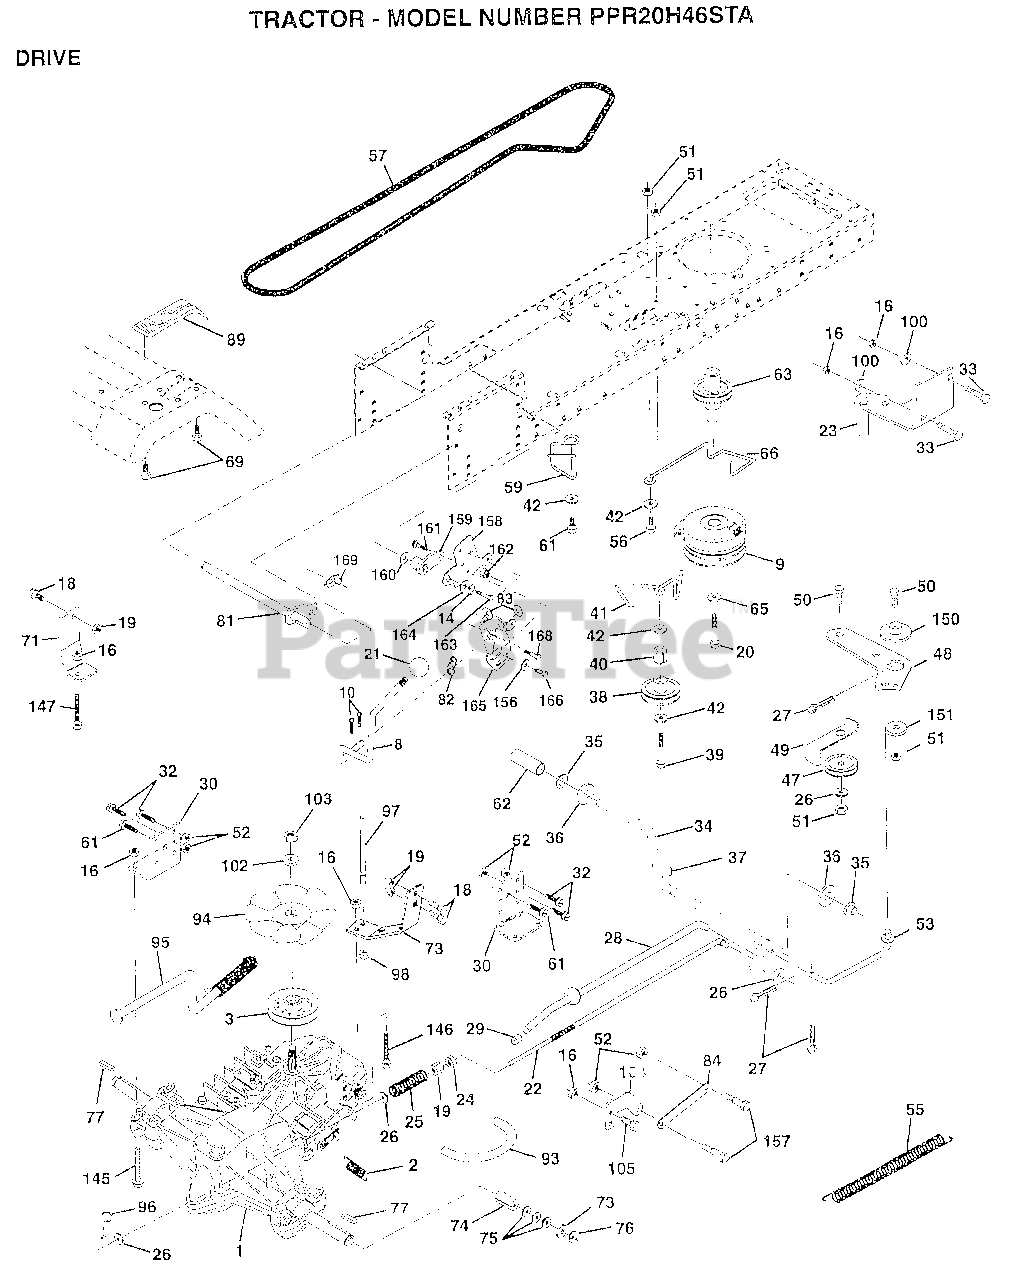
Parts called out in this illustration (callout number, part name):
2	SPRING RET BRAKE
3	PULLEY.TRANSAXLE
8	ROD.SHIFT.FEND.ADJ.YT
9	CLUTCH.ELECTRIC
10	PIN COTTER 1/8
14	LOCKWASHER
16	NUT
18	BOLT
19	NUT
20	BOLT.7/16-20X4.25
21	KNOB DLX BLK/BLK
22	ROD.BRAKE.HYDRO.
23	BRACKET.CLUT.MTG.
24	NUT
25	SPRING ROD LT
26	WASHER
27	COTTER PIN
28	ROD.BRAKE.PARK.LT
29	PLUNGER CAP T
30	TRANSAXLE MTG BKT
32	BOLT
33	BOLT
34	SHAFT ASM-PEDAL F
35	NYLON BEARING
36	WASHER LT
38	FLAT IDLER PULLEY
39	BOLT
40	SPACER T
41	"KEEPER,BELT.IDLER FLAT"
42	WASHER
48	BELLCRANK.CLUTCH
49	RETAIN BELT
53	"LINK, CLUTCH T"
55	"SPRING, RETURN LT"
57	"BELT.GD DRV 82"""
59	KEEPER BELT CNTSP
61	SCREW
62	PEDAL COVER T
63	PULLEY.CLUTCH.EVX
65	LOCKWASHER
66	KEEPER-BELT
69	SCREW HEXWSH H-L
71	STRAP TORQ LH HYD
73	"STRAP-TORQUE,RH"
74	SPACER SPLIT
75	WASHER
76	E-RING LT
77	SQUARE KEY
78	WASHER
81	SHAFT.ASM.CROSS
82	"SPRING,TORSION"
83	WASHER
84	LINK.TRANSAXLE.LT/YT
89	CONSOLE.SHIFT.AUTO.YT/GT.BLACK
93	"LINE FUEL HYD 4"""
94	"FAN 7"" HYDRO"
95	CONTROL.ASM.BYPASS.HYDRO.99
96	RETAINER M
97	BOLT KEEPER RH
98	NUT
100	WASHER M
102	WASHER BELLEVILLE
104	ARM CONTROL HYDRO
105	SCREW CAP 5/16-18
145	BOLT.HEX.FLGHD
146	BOLT.HEX.FLGHD.
147	BOLT.HEX.FLGHD
150	BUSHING.BELLCRANK.GRD.DR
151	WASHER
156	WASHER.SRRTD.5/16
157	"BOLT,SHOULDER"
158	BRKT.SHIFT.MOUNT
159	HUB.SHIFT
160	WASHER
161	BOLT T
164	WASHER.5/8X.281X10GA
165	BRKT.PIVOT.LEVER
166	SCREW.5/16-18X5/8
168	BOLT.SHOULDER.5/16-18X.561
169	PLATE.FASTENING
